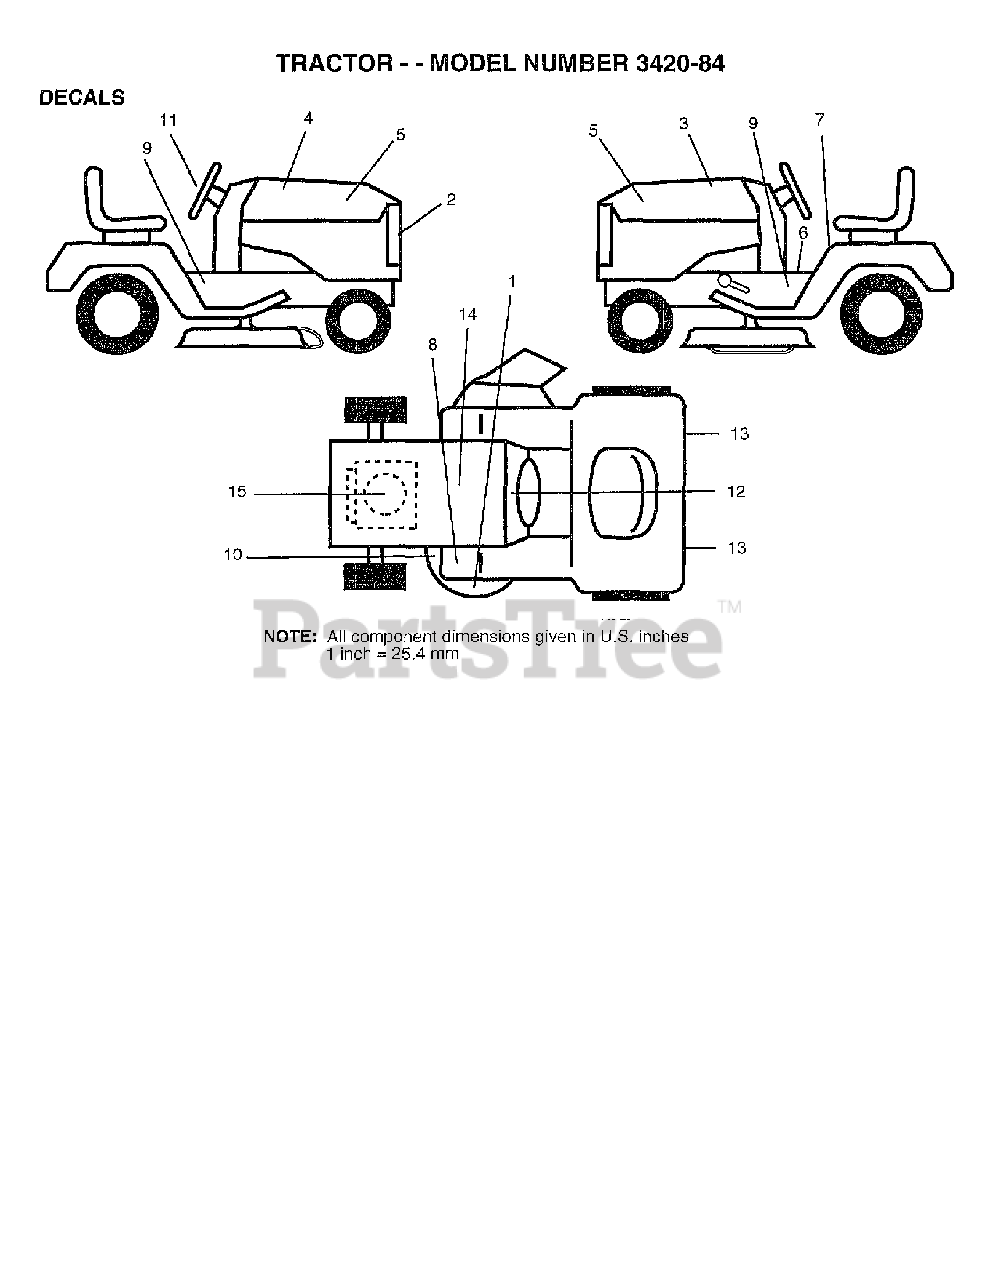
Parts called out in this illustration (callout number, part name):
2	Poulan TBD
3	Poulan TBD
4	Poulan TBD
5	Poulan TBD
6	DECAL PARK BRAKE
9	Poulan TBD
10	DECAL V BELT SCHEMATIC
11	Poulan TBD
13	REFLECTOR-TAIL YT
14	DECAL BTRY SYMBOLS
15	Poulan TBD
